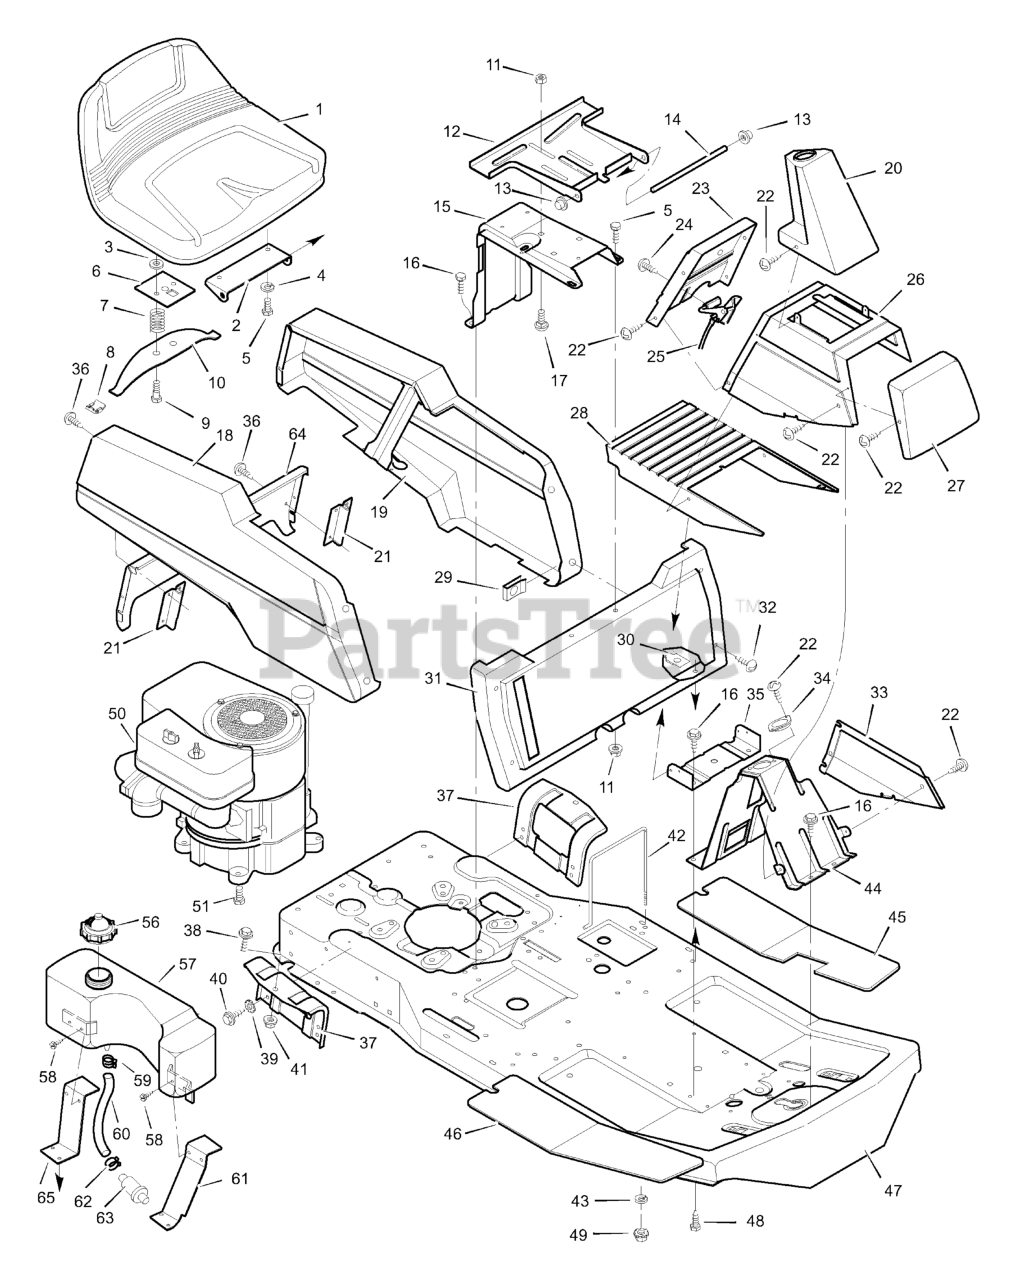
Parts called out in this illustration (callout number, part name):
2	Hinge, Seat
3	Retainer
4	LOCKWASHER
5	BOLT, Hex
6	Plate, Seat Switch
7	SPRING, Compression
8	Glide, Seat Spring
9	BOLT, Shoulder
10	SPRING, Seat
11	Locknut, Flange
12	BRACKET, Seat Pivot
13	Cap, Push On
14	ROD, Seat Hinge
15	SUPPORT, Seat
17	BOLT, Carriage
18	PANEL, Right Side
19	PANEL, Left Side
20	Cover, Steering Column
21	BRACKET, Panel
22	SCREW, Tapping
23	PANEL, Control
25	Throttle Control
27	Cap, Front Console
28	Cover, Lower Console
29	Retainer
31	PANEL, Front
32	SCREW, Southco
33	PANEL, Left Access
34	BEARING, Steering Post
35	BRACKET, Cover Mounting
37	SUPPORT, Body
38	BOLT, Shoulder
39	LOCKWASHER
41	Locknut, Flange
42	Clamp Assembly, Battery
44	SUPPORT, Steering Column
45	Mat, Left
46	Mat, Right
49	Locknut
50	Engine
51	BOLT, Engine Mount
56	Cap, Fuel
57	Tank, Fuel
58	SCREW, Hex
59	Clamp, Hose
60	LINE, Fuel
61	BRACKET, Remote Tank (Front)
62	CLAMP, Gas Line
63	Filter, Fuel
64	PANEL, Rear
65	BRACKET, Remote Tank (Rear)
